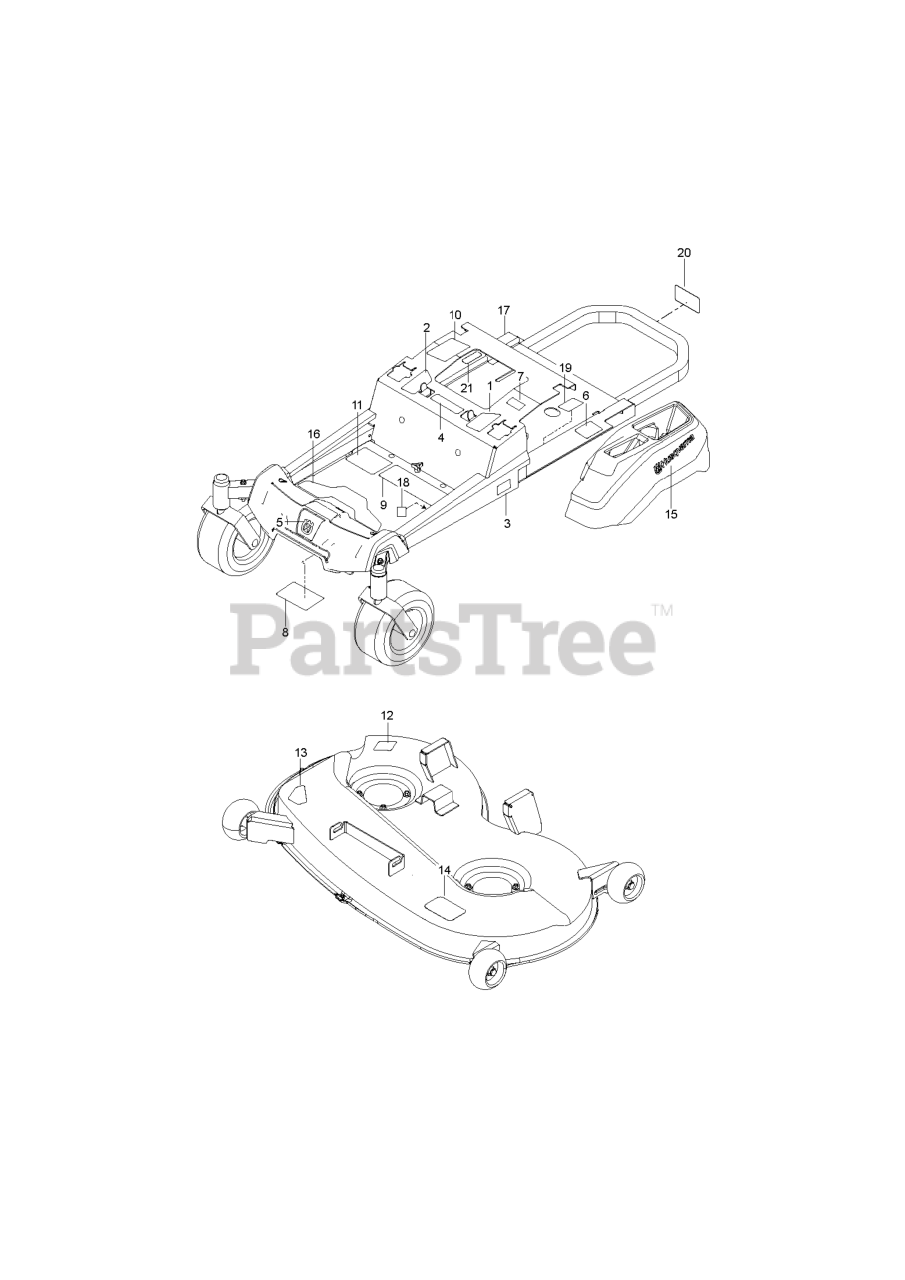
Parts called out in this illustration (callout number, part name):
1	DECAL.ZTR.RZ.THRTL/PRKBRK.V2.L
2	DECAL.ZTR.RZ.THRTL/PRKBRK.V2.R
3	DECAL.ZTR.SIDERAIL.Z246.HUSQ
4	EURO DECAL-BATTERY WARNIN6
5	DECAL.BADGE.55MM.CROWNH.HUSQ
6	DECAL, DO NOT TOW
7	DECAL, EXITING MOWER
8	DECAL, SERVICE
9	DECAL ZTR WARNING DECAL DECAL.
9	DECAL.ZTR.WARNING.SMARTIGNITIN
10	DECAL, CUSTOMER RESPNSIBILITY
10	DECAL.WARNING.CUST.RESP.E85.
11	DECAL.ZTR.STARTINS.READYSTART
11	DECAL.ZTR.STARTINSTRCT.CHOKE15
12	DECAL.DECK.6MIL./DEF.SHLD.WARN
12	DECAL, DECK DEFLECTOR, WARNING
13	DECAL.DECK.6MIL./DEF.SHLD.WARN
13	DECAL, DECK DEFLECTOR, WARNING
14	DECAL, BELT ROUTING
15	DECAL.HUSQVARNA.210MM
16	PAD.RZ.FOOTREST.PLATE
16	DECAL ZTR BRAND GRAPHIC DECAL.
17	DECAL CERTIFICATION DECAL EMCC
18	DECAL.80.DBA.AUSTRALIA
19	DECAL.EPA.EMISS.LABEL.ZTR.18
20	DECAL, PROP. 65
21	DECAL, WARNING SPARK ARRESTOR
